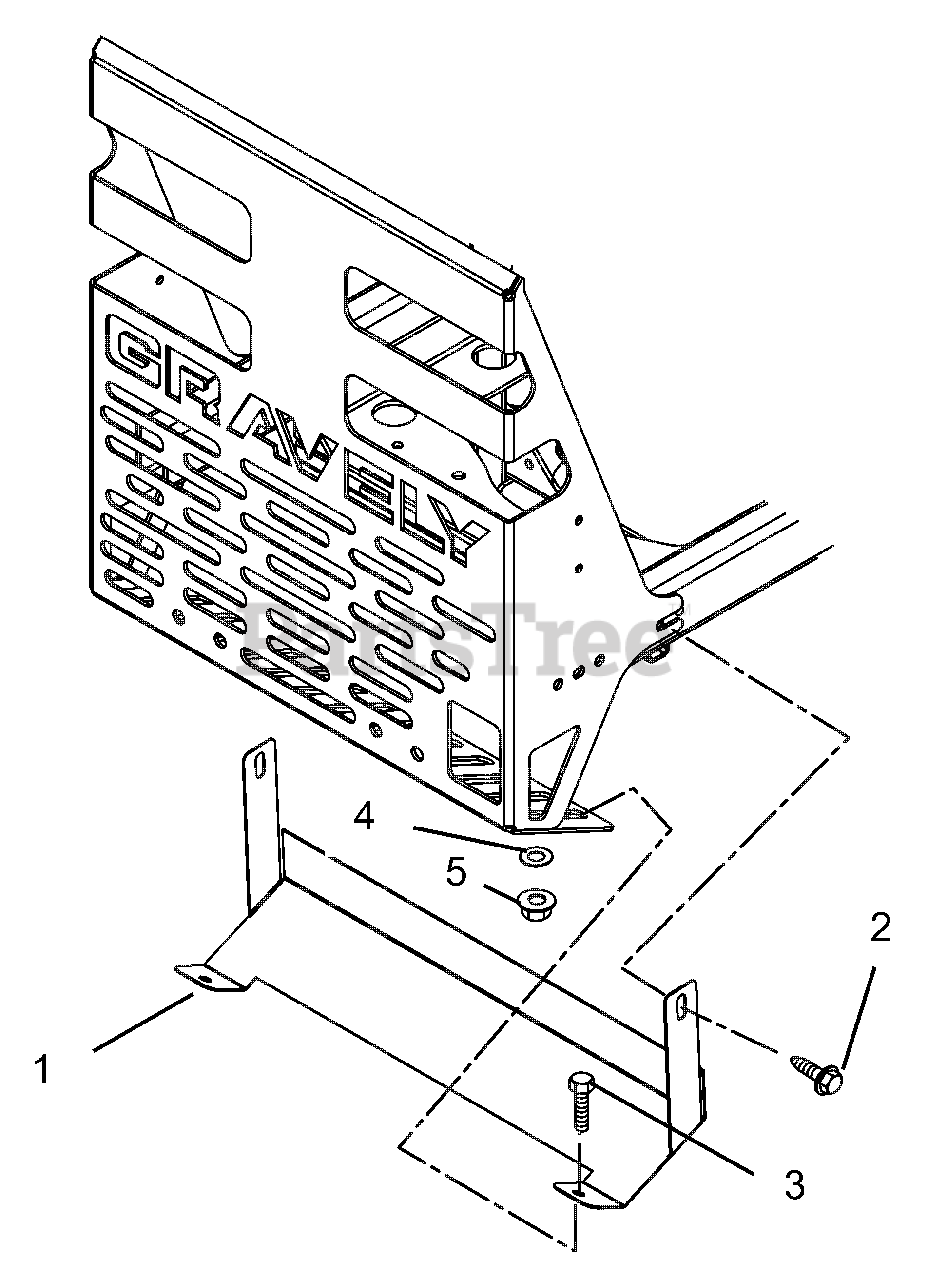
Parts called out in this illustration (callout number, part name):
1	Shield - Heat - IZ (Kit 591007)
2	.38-16 x .50" Hex Washer Head Tap Screws
3	.38-16 x 75 Hex Bolt
4	.438" x 1.00" x .083" Flat Steel Washer
5	.38-16 top Flange Lock Nuts
